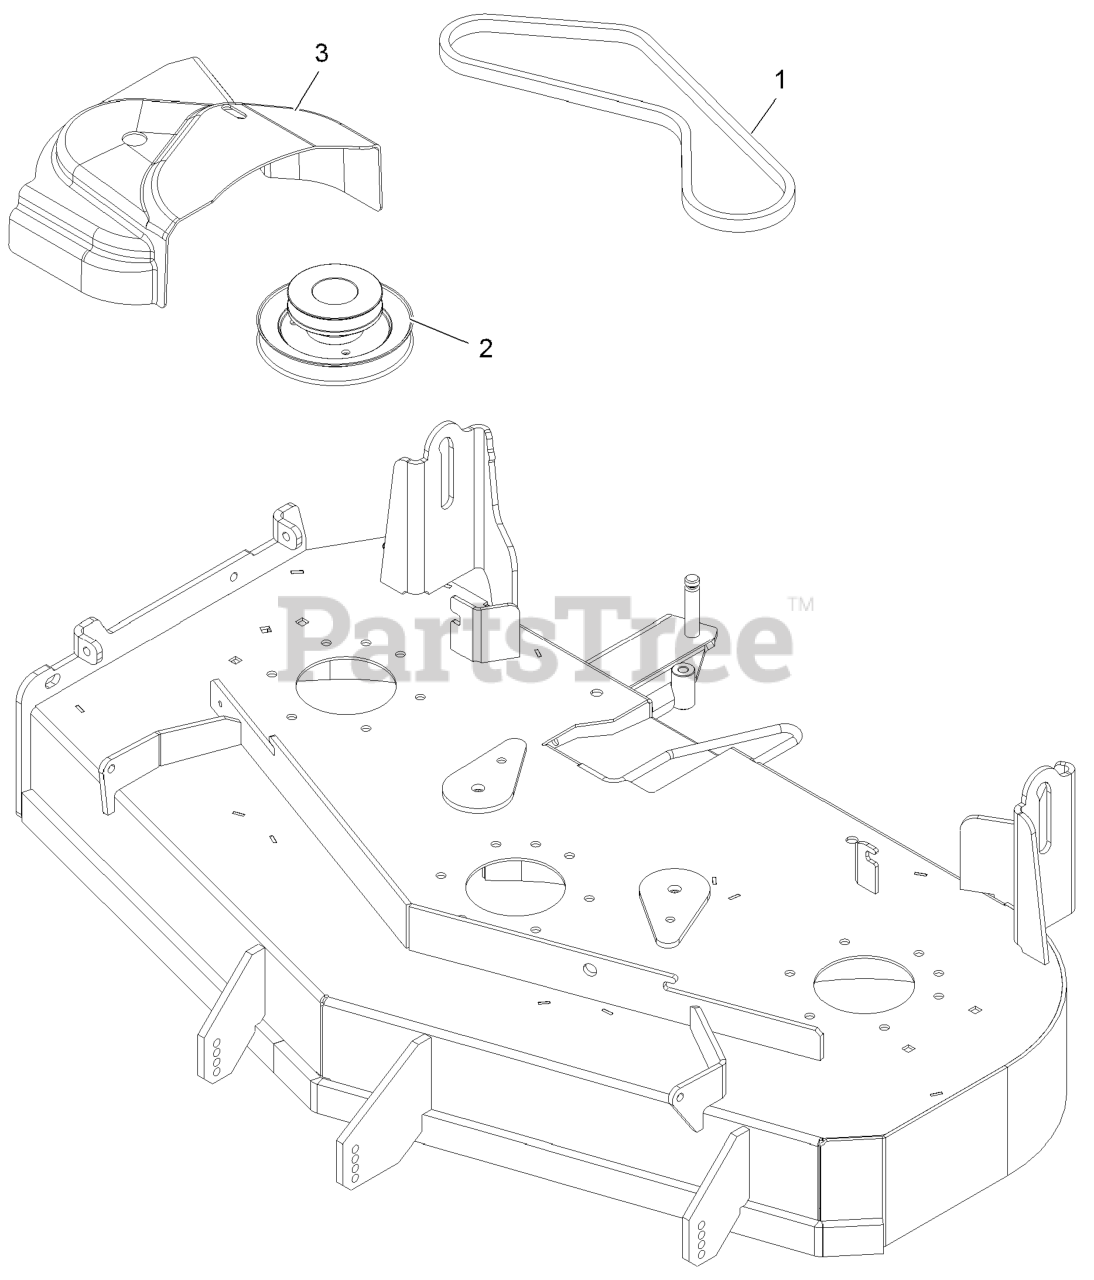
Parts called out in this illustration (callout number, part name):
1	Belt, Blower (48")
2	Jackshaft-Uv Drive, 484 Splined
3	Cover,Belt Uv 48
